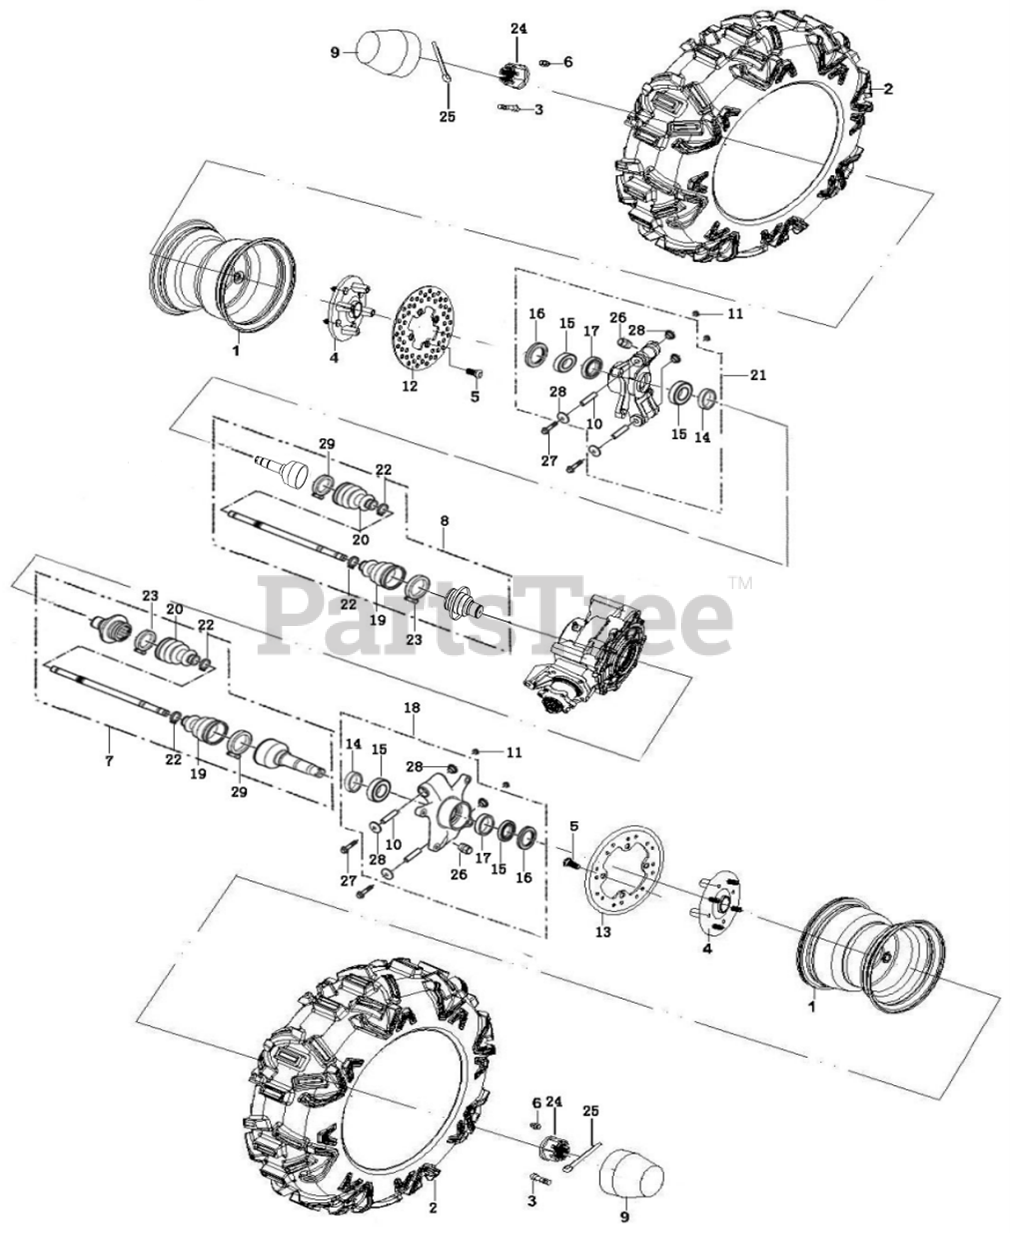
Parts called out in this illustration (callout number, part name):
1	RIM-REAR (14x)8
2	TIRE (REAR CARLISLE)
3	VALVE-CYCLE
5	BOLT M8X15-15X5
6	TAPER NUT M10X1.25
7	CV SHAFT-REAR (LH)
8	CV SHAFT-REAR (RH)
9	HUB DUST COVER
10	STEERING KNUCKLE TUBE (REAR)
11	LOCK NUT M10X1.25
12	DISC BRAKE - REAR RIGHT
13	DISC BRAKE - REAR LEFT
14	REAR KNUCKLE INSIDE OIL SEAL
15	BEARING 6206RS
16	REAR KNUCKLE OUTSIDE OIL SEAL
17	REAR STEERING KNUCKLE TUBE
18	STEERING KNUCKLE (REAR LH)
19	RUBBER BOOT
20	AXLE RUBBER BOOT
21	STEERING KNUCKLE (REAR RH)
22	CLAMP - LARGE
24	SLOTTED NUT M24X1.5
25	COTTER PIN 3.2X50
26	KNUCKLE OIL FITTING
27	HEX HEAD FLANGE BOLT M12X1.25-110
29	CLAMP - LARGE
